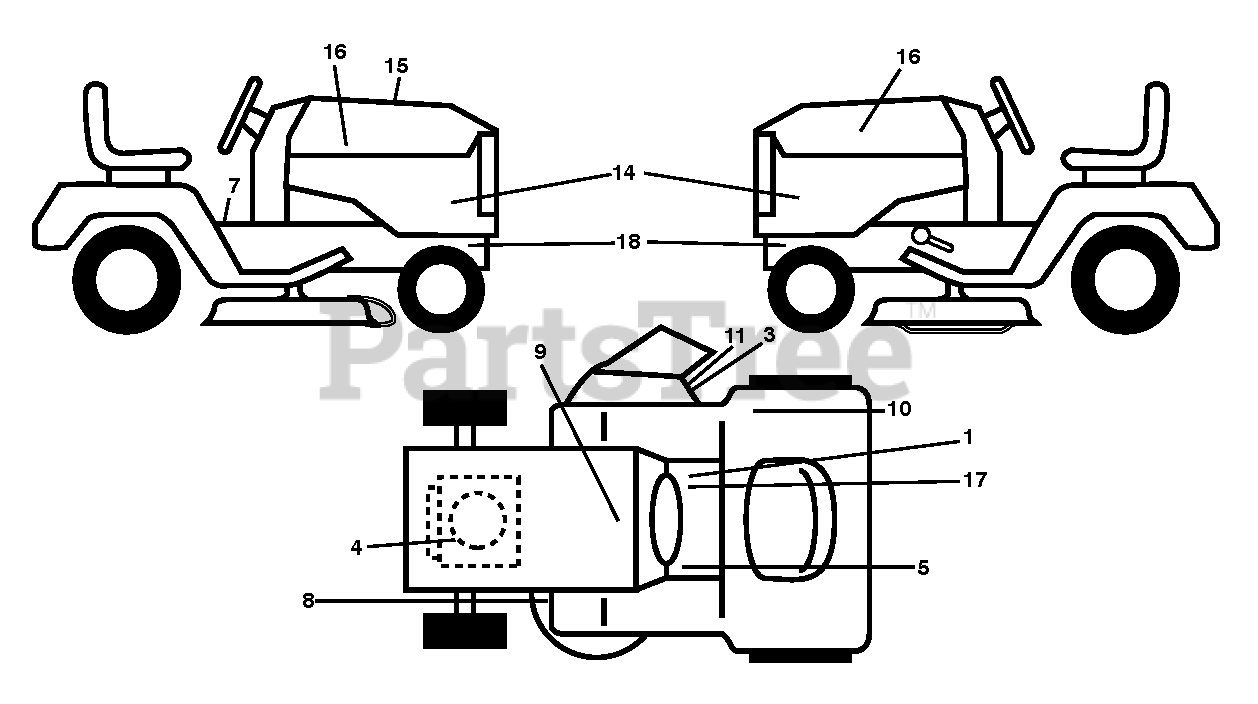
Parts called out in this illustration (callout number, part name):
1	DECAL.PEDALS.SYMBOL
3	DECAL.DFLCTR.WARNNG.CTFNGR.SYM
4	DECAL.ENGINE.WARNING
5	DECAL.FNDR.SDLE.BRAKE.CLUTCH.6
7	DECAL.READ.OWN.MAN.SYMBOL.LT
8	DECAL.MOWER.SCH.48/54.PREM
9	DECAL BTRY SYMBOLS
10	DECAL.FENDER.105DB/CE.
11	DECAL.CUTFINGER.CE.02
16	RP.DECAL.BADGE.170MM.TEXTLOGO
17	DECAL.PARKING.BRAKE.SADDLE.LT
18	DECAL.CHASSIS.HOT.MUFFLER
